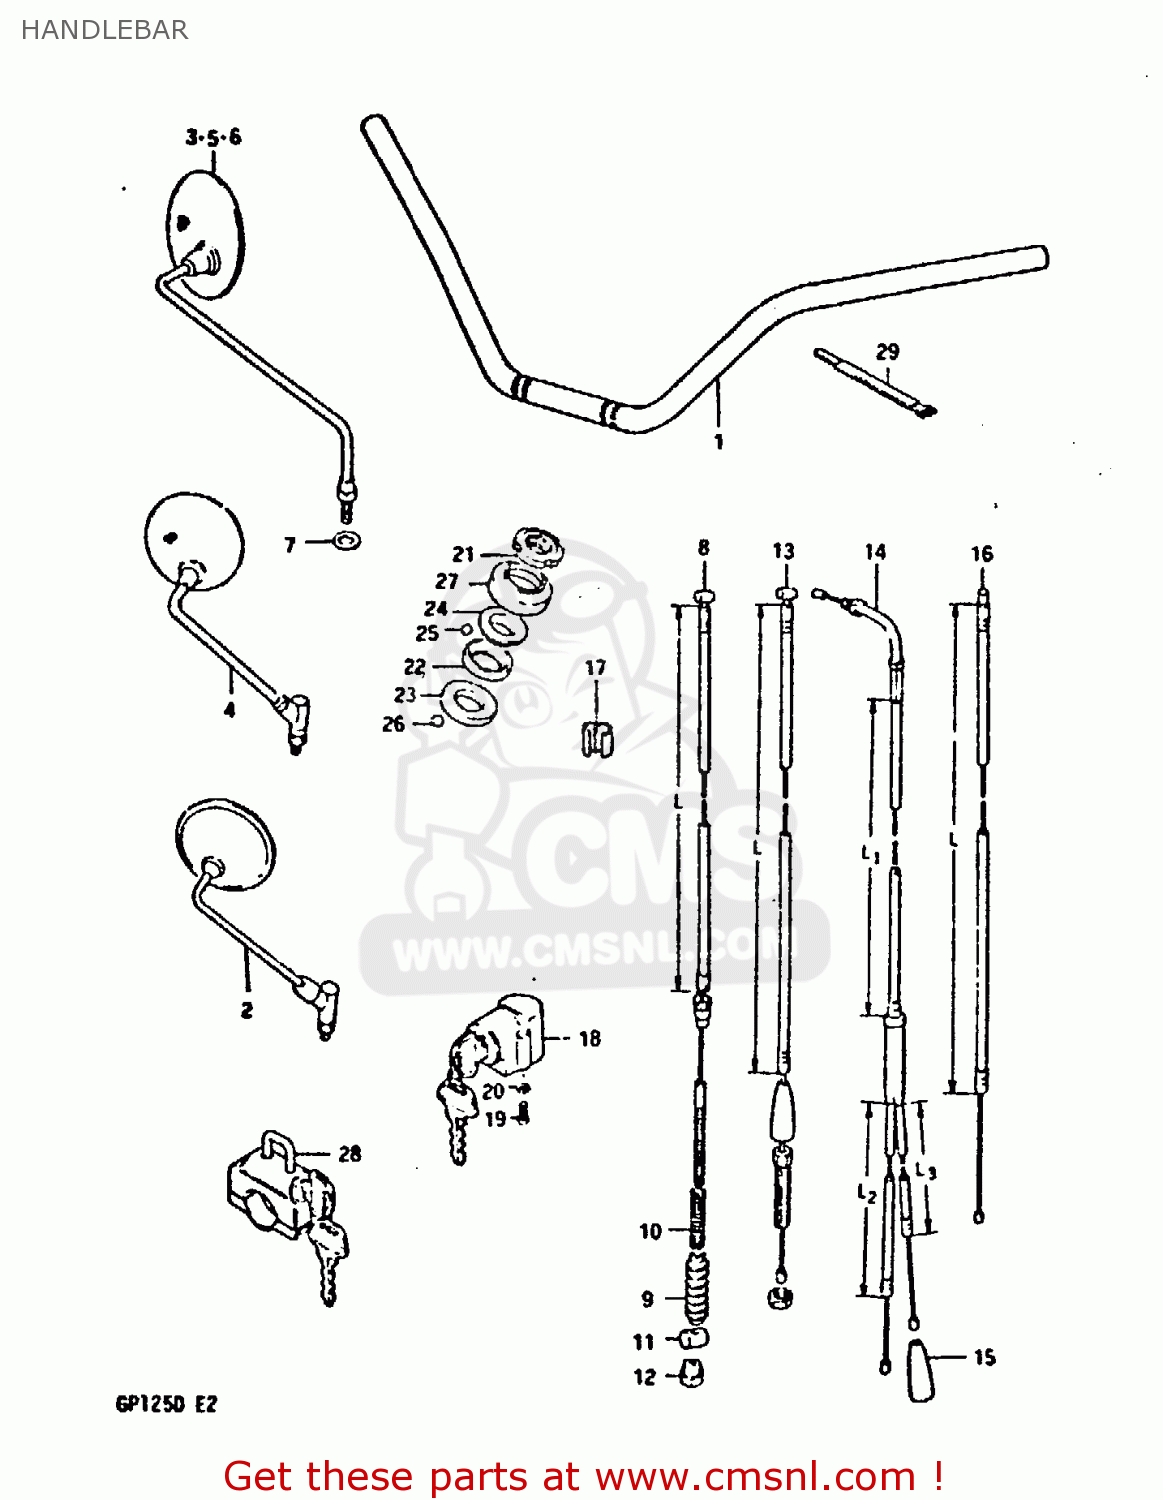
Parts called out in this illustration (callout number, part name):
1	HANDLEBAR
2	MIRROR ASSY, REAR VIEW
3	MIRROR ASSEMBLY,RIGHT
7	WASHER
13	CABLE ASSY, CLUTCH (L:900)
14	CABLE ASSY, THROTTLE (L1:545, L2:320, L3
15	SEAL,DUST(7X18X30)
16	CABLE STARTER
17	CLIP
18	LOCK ASSY,STEERING
19	SCREW
20	LOCK WASHER
21	NUT,STEERING STEM(25X44X10)
22	RACE,STEERING INNER UPR
23	LACE,STEERING INNER LWR
24	RACE,STEERING OUTER UPR
25	BALL
26	BALL
27	DUST SEAL,STEERING UPR
28	LOCK ASSEMBLY,HELMET
29	CLAMP
